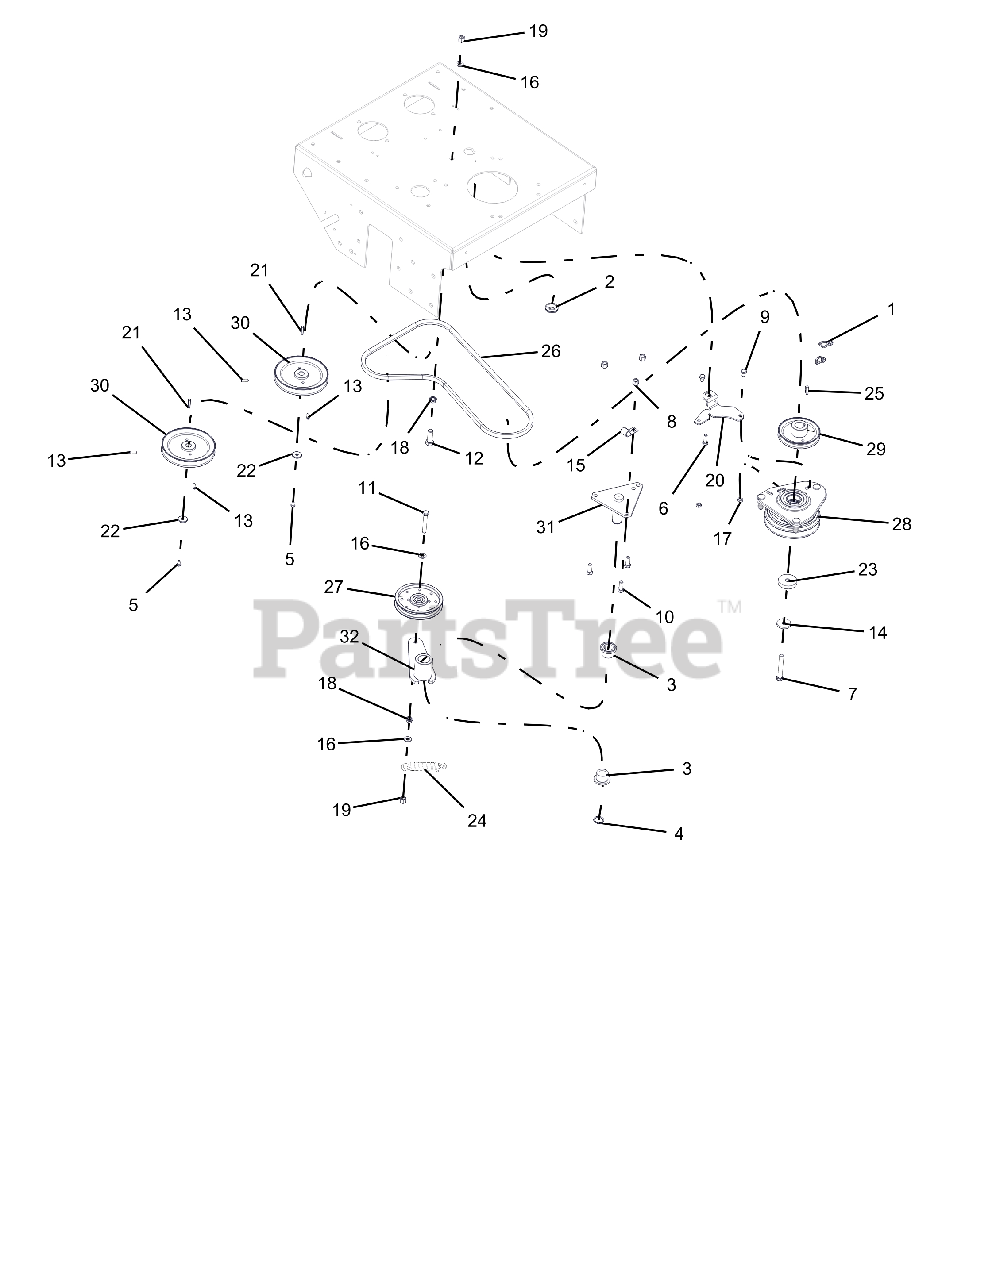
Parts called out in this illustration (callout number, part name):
1	CABLE TIE, .15 X 8.50
2	GROMMET:RUB:.88IDx1.38ODX.14GR
3	BRG, FLANGE 1.00 X 1.25 X 1.00
4	SNAP, RING, 1.00 X .042 EXT
5	BLT-HEX M6 X 1.0X10 YWZC
6	BLT-HEX .31-18X1.00 GR5 YWZC
7	BLT-HEX .44-20X3.00 GR8 YWZC NYTORQ
8	NUT-LK-NYL .38-16 YWZC
9	BLT-HEX .31-18X.50 GR5 YWZC
10	BLT-HEX .38-16X1.00 GR5 YWZC
11	BLT-HEX .38-16X2.50 GR5 YWZC
12	BLT-HEX .50-13X1.50 GR5 YWZC
13	SCR-SET, 25-20X.75 SKHCUPDL REV
14	WSHR, 7/16" SPRING DISC
15	P-CLIP, .500 INSULATED
16	WSHR-FL-STL.406X.812X.065 YWZ
17	@NUT-LK-CTR-JAM .31-18 YWZC
18	@NUT-SPNLK-FLG .375-16 YWZC
19	NUT-LK-NYL .38-16 YWZC
20	PLATE, CLUTCH DOG
21	KEY, RND - M5XM5XM30
22	WASHER, .250 WIDE HEAVY FLAT Y
23	SPCR, .450 X 2.00 X .396
24	SPRG, EXTENSION
25	KEY, .250 X .250 X .995 TPR
26	BELT, HA 55.1 EL AMD OHR
27	PULLEY, FLAT 4.50 X .375 W/BRG
28	CLUTCH ASSY, OGURA
29	PULLEY, V-BELT WLK TRANS DRIVE
30	PULLEY, V-BELT PUMP HYD WLK
31	WLDMT, IDLER PIVOT MOUNT
32	WLDMT, IDLER ARM
